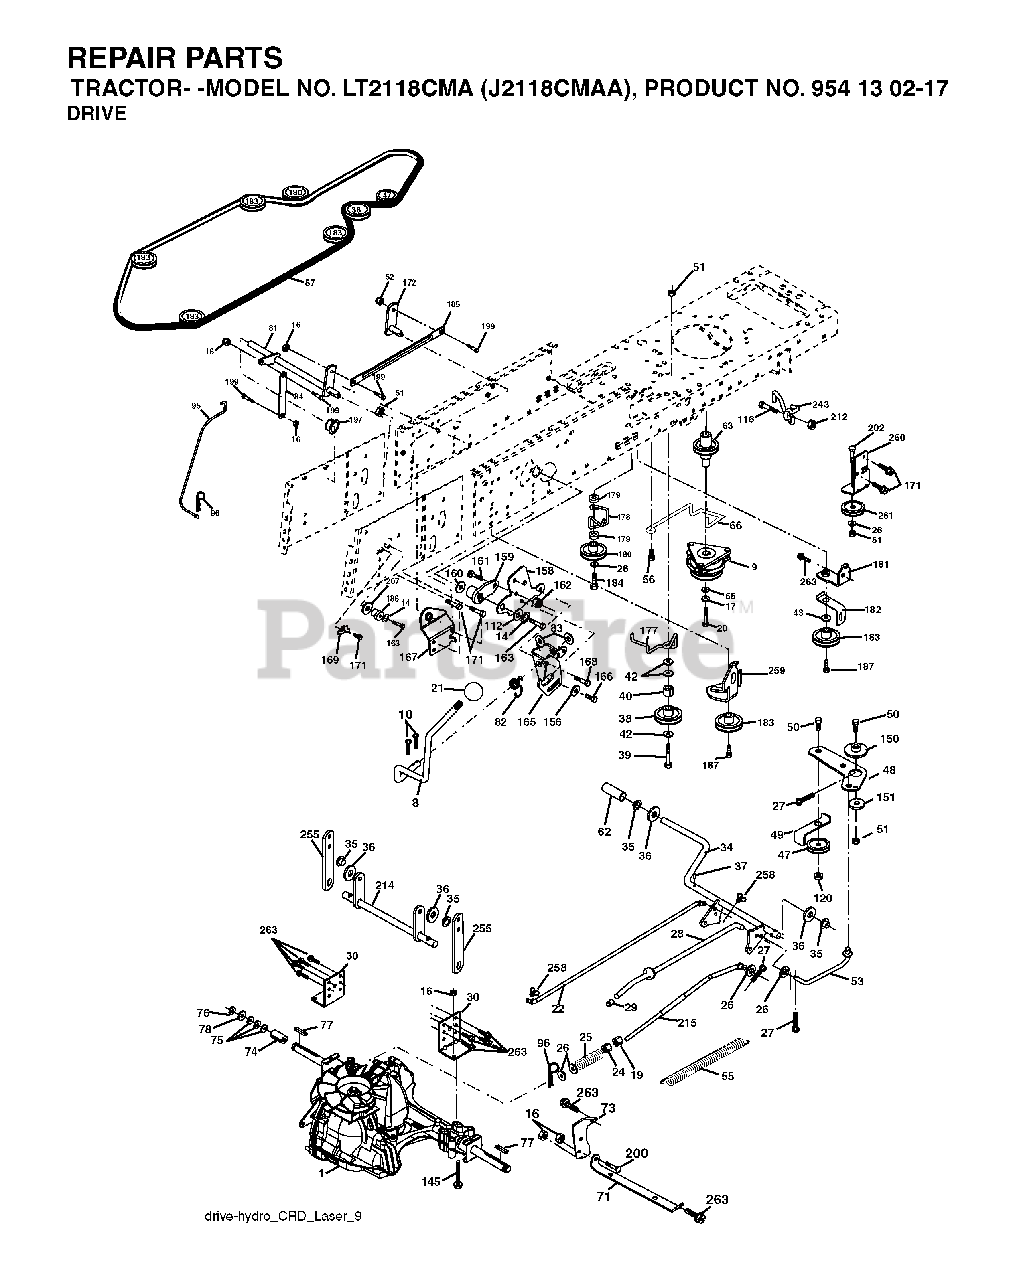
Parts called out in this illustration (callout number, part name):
8	ROD SHIFT
10	PIN COTTER
14	LOCKWASHER
16	NUT.71038.31-18.HEX.NYLOCK
17	LOCKWASHER
19	NUT
20	BOLT HEX 7/16-20X4-1/4"
21	PISTOL KNOB
24	NUT
25	SPRING ROD LT
27	COTTER PIN
28	ROD, PARKING BRAKE
29	PLUNGER CAP
30	BRKT, TRNSXLE MNT 20"
34	SHAFT, FOOT PEDAL
35	BEARING.NYLON
36	WASHER LT
37	DRIVE PIN
38	PULLEY.FLAT
42	WASHER
47	IDLER PULLEY
48	BELLCRANK, CLUTCH
49	RETAIN BELT
50	BOLT.3/8-16X1.50
51	LOCKNUT
52	LOCKNUT
53	LINK, CLUTCH LT
55	SPRING, RETURN LT
56	SCREW.3/8-16
62	PEDAL COVER T
66	KEEPER BELT ENGINE
71	STRAP TORQUE LH HYDRO
73	STRAP TORQUE RH HYDRO
74	SPACER AXLE
76	E-RING LT
77	SQUARE KEY
81	SHAFT ASSY
82	SHIFT SPRING
83	WASHER
96	RETAINER M
112	WASHER LT
116	BOLT D
120	NUT LOCK FLG 3/8-16 UNC
145	BOLT HEX 5/16-18 GR 5
150	BUSHING.BELLCRANK.GRD.DR
151	WASHER 12/32X2X10GA
156	WASHER.SRRTD.5/16
158	BRACKET
159	HUB.SHIFT
161	BOLT
162	NUT.CROWNLOCK.1/4
165	RP BRACKET
167	BRACKET
168	BOLT.SHOULDER.5/16-18X
169	PLATE.FASTENING.CROSS.SHAFT
180	PULLEY.FLAT.IDLER
184	SCREW.HXWSH.3/8
187	BOLT.5/16-18X1.25
197	NYLINER SNAP 5/8" ID
199	BOLT SHOULDER 5/16-18 UNC
200	BOLT
202	BOLT
207	WASHER NYL
212	NUT
243	BRKT ASM MTNG
258	CLIP RETAINER
261	FLAT IDLER PULLEY
263	SCREW, 3/8-16X3/4
